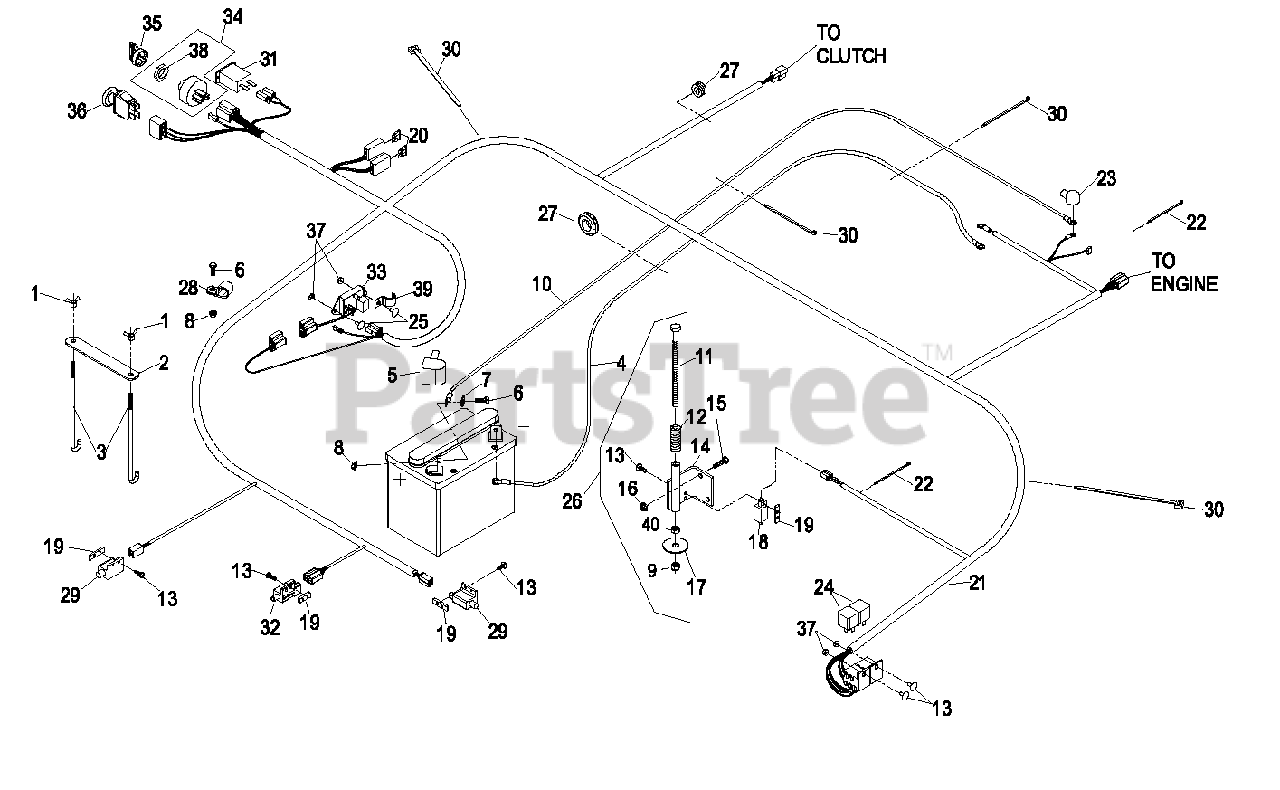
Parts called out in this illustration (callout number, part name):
1	WINGNUT
2	STRAP-HOLDDOWN, BATTERY
3	BOLT-HOLDDOWN
4	CABLE-GROUND, NEGATIVE
6	SCREW-HH
7	WASHER-FLAT
9	NUT-LOCK, NI
11	SCREW-HH
12	SPRING-SWITCH, SEAT
13	SCREW-PPH
14	BRACKET-SWITCH, SEAT
15	SCREW-HH
18	SWITCH-CLOSED, NORMALLY
19	PLATE-TAPPED
20	FUSE-BLADE TYPE, 20 AMP
21	HARNESS,WIRE LHP KC
22	TIE-CABLE
23	INSULATOR-SOLENOID
25	SCREW-HEAD, TRUSS
26	ASM,SEAT SWITCH ACTUATOR
27	GROMMET
28	CLIP-LOOM
29	SWITCH-OPEN, NORMALLY
30	TIE-PLASTIC
31	METER-HOUR
33	MODULE-DELAY, SEAT
34	ASM,SWITCH W/NUT
35	KEY-IGNITION
35	KEYS-IGNITION (SPARE PAIR
36	SWITCH-PTO
37	NUT-LOCK, NI
38	NUT-SWITCH, IGNITION
39	CLIP-HALF, LOOM
40	NUT-HEX
